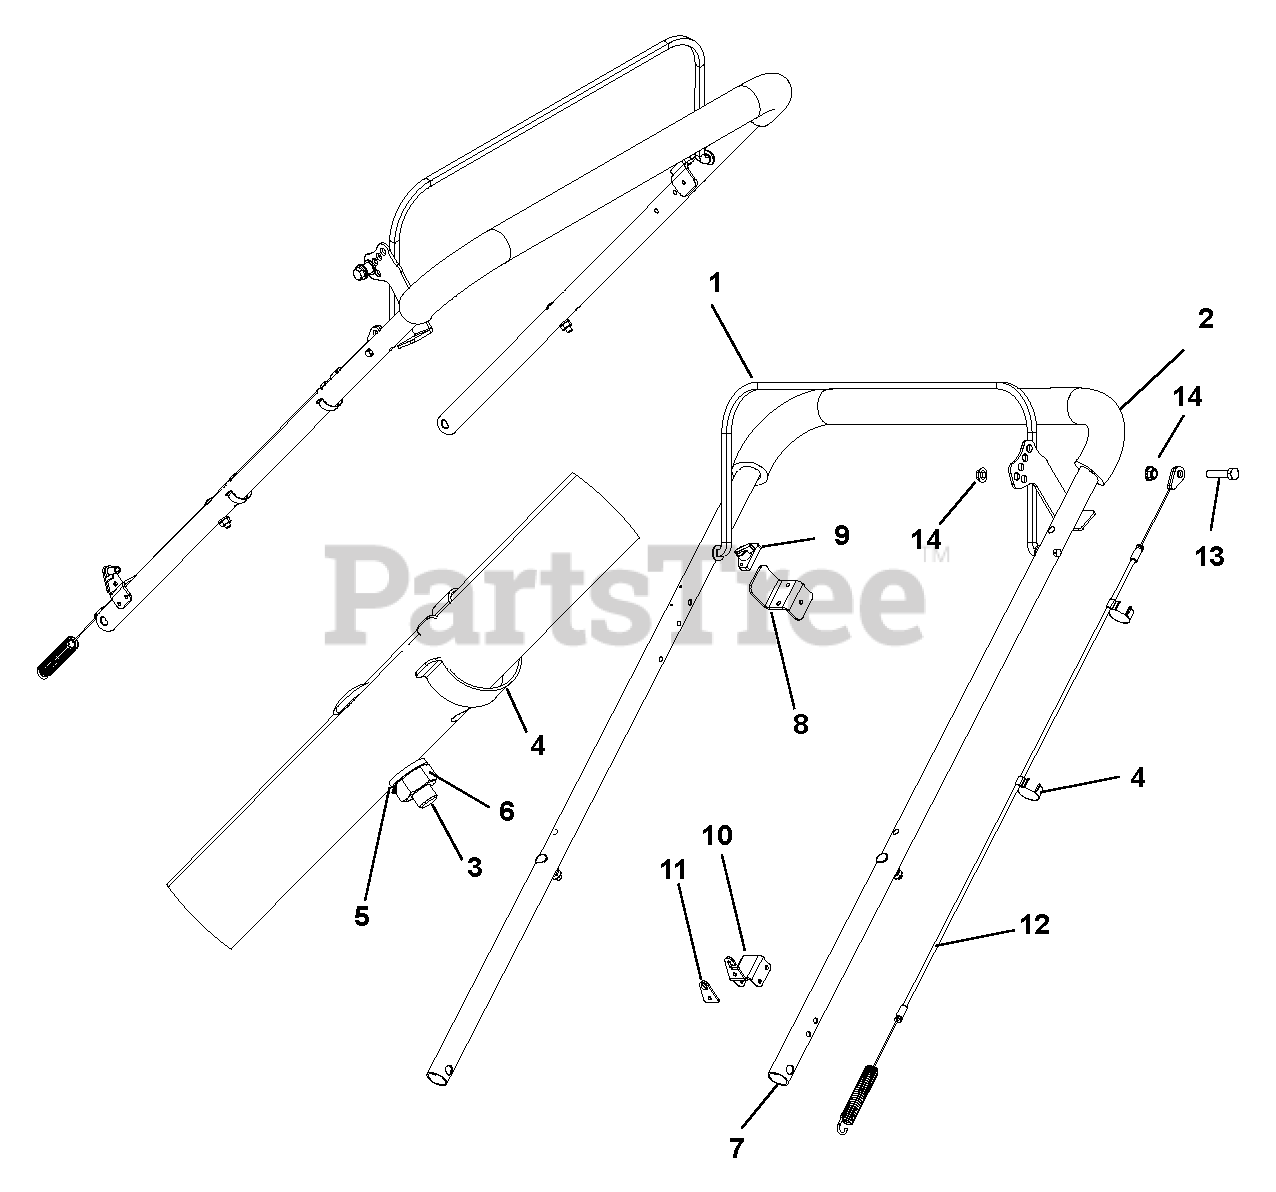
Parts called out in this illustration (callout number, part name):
1	PR-Safety Bail Assembly
2	Sleeve Handle
3	Bolt, Cont Head 1/4-20 x 1.50
4	Snap Mount
5	Washer, Lock .250
6	Hex Nut, 1/4-20
7	Handle, Dethatcher
8	Switch Bracket
9	Switch Assembly
10	Cable Mount
11	Cable Lock
12	Cable, Clutch, Dethatcher
13	Bolt, Hex .31-18 x 1.75 Grade 5
14	Nut, Spin Lock, Flange .312-18
